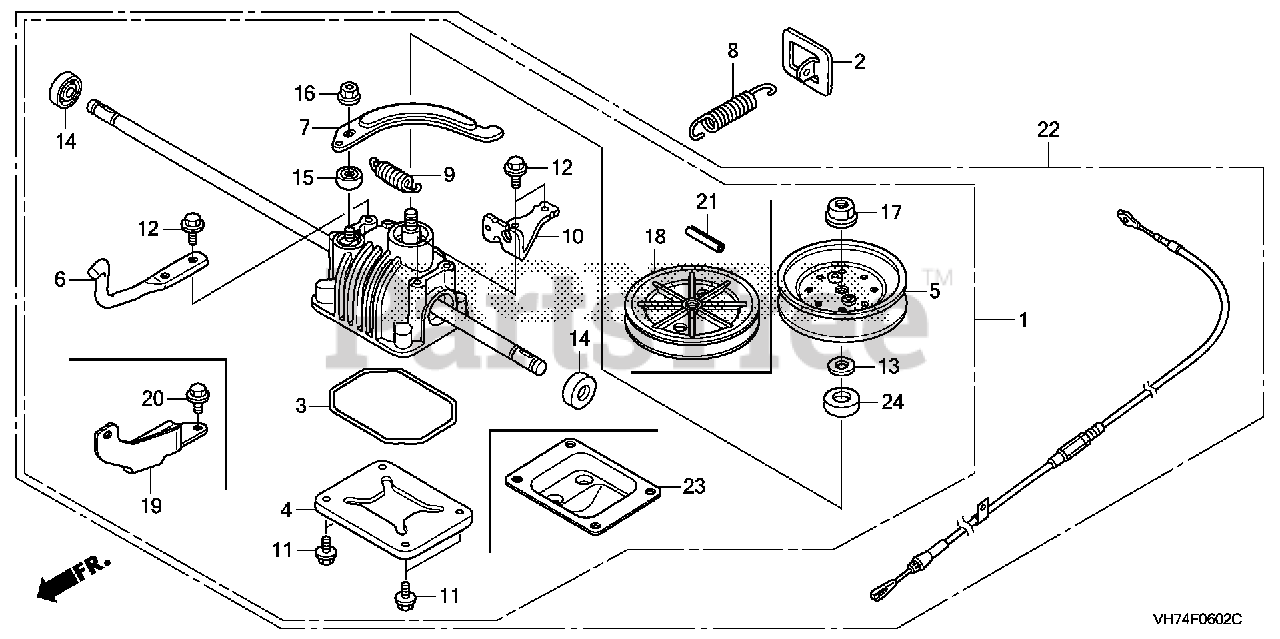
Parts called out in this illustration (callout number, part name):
1	TRANSMISSION ASSY.
2	PLATE, TENSION SPRING
3	O-RING, CASE
4	COVER, REDUCTION
7	ARM, CONTROL
8	SPRING, WHEEL TENSION
9	SPRING, RETURN
10	HOLDER, WIRE
11	BOLT, FLANGE (6X12) (CT200)
12	BOLT, FLANGE (6X12) (CT200)
14	OIL SEAL (12.7X28.6X6.4)
14	OIL SEAL (12.7X22.2X6.4)
15	OIL SEAL (10X19X7)
16	NUT, FLANGE (6MM)
18	PULLEY, DRIVEN
19	ARM, TENSIONER
20	BOLT, FLANGE (6X12) (CT200)
21	PIN, SPRING (5X36)
22	TRANSMISSION KIT
23	COVER, REDUCTION
24	OIL SEAL (12.7X28.6X6.4)
